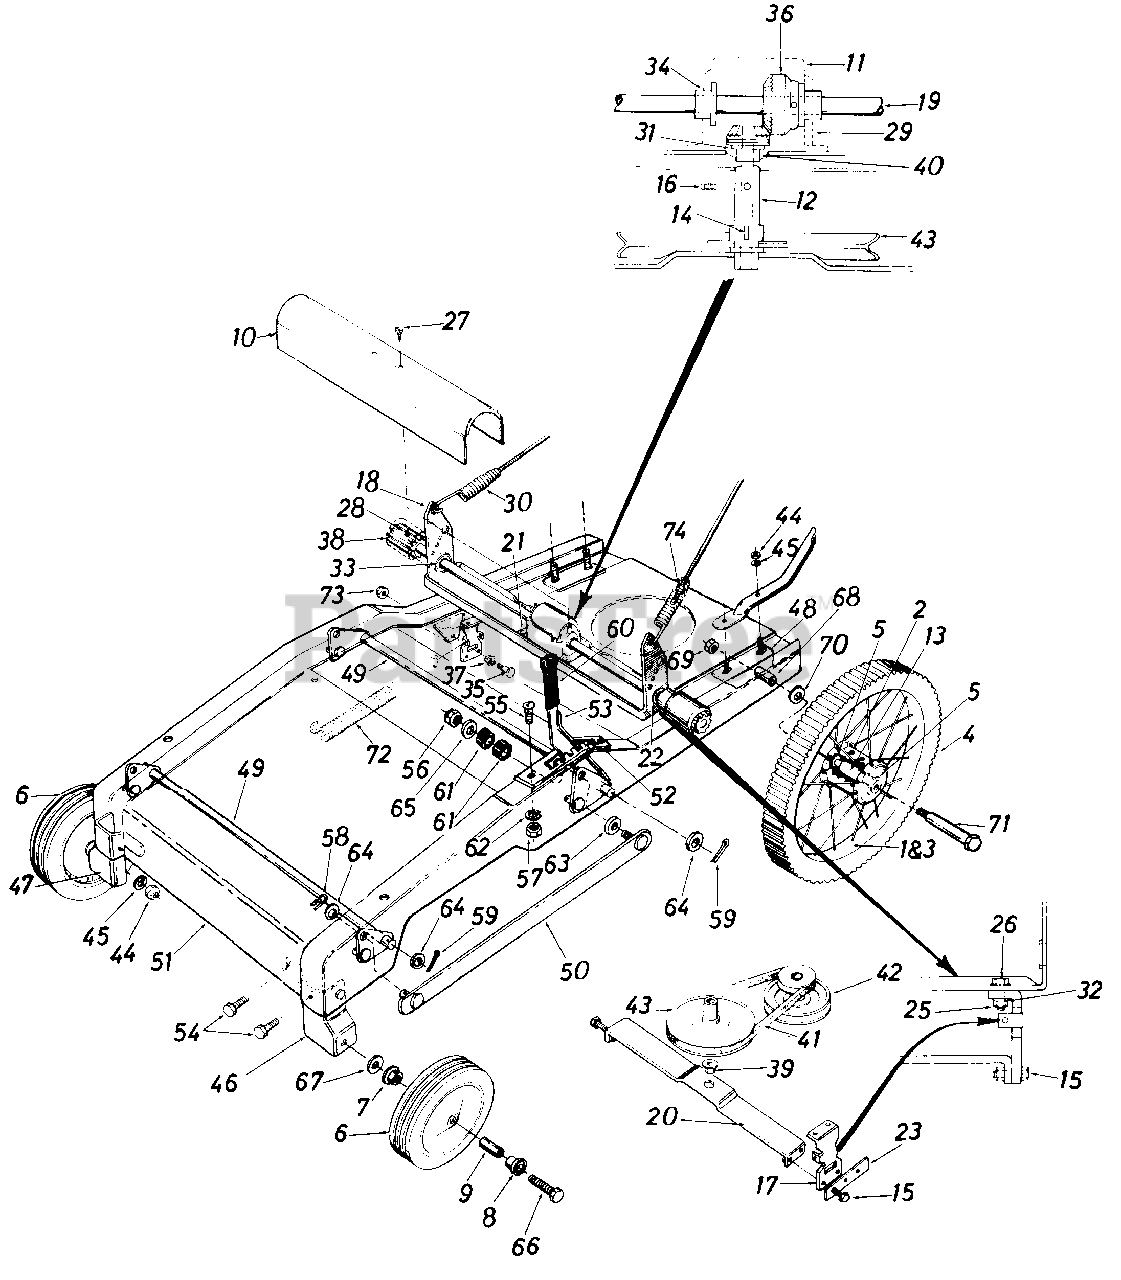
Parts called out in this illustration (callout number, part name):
1	16" Wheel Ass'y. Comp. Rear
2	Oil Cap
3	Rear Wheel Rim Only
4	Rear Wheel Ti re Only 16 x 1 .75
5	Ball Brg..630" I.D.
6	Wheel Ass'y. Comp. Front 8 "
7	Flanged Ball Brg. 3/8 I.D.
8	Flanged Ball Brg. 1/2" I.D.
9	Spacer 3/8 I.D
10	Top Drive Frame Cover
11	Gear Box Cover
12	Pinion Ass'y.
13	Wheel Spacer
14	#2 Wood ru f f Key 3/32 x 1/2" Dia. Hdn.
15	Hex Sems Bolt 5/16-18 x 1.00" Lg.
16	Set Scr. 5/16-18 x .25" Cup
17	Bottom Drive Frame
18	Top Drive Frame Ass'y.
19	Drive Shaft
20	Bottom Drive Frame Ass'y.
21	Hex Self-Tap Scr. 1/4-20 x .62" Lg.
22	Collar 5/8" I.D.
23	Drive Frame Stop
25	Hex Nut 5/16-18 Thd.
26	Hex Sems Bolt 5/16-18 x .75" Lg.
27	Hex Wash. Hd. AB-Tap Scr. #8 x .50" Lg.
28	Spring Pin 3/16" Dia. x 1.12" Lg.
29	Gear Box
30	Extension Spring
31	"O"-Ring
32	L-Wash. 5/16" I.D.
33	Ball Brg. .630" I.D.
34	Flange Brg. .630" I.D.
35	Shld. Bolt .443" Dia. x .330
36	Bevel Gear.62" I.D. 28 Teeth
37	Pivot Slide
38	Drive Pinion
39	Hex Flange Brg. .503" I.D.
40	Flange Brg. .503" I.D. w/G roove
41	3V-Belt 28" Lg.
42	Double Pulley
43	3/8" V-Pulley .502" I.D. x 6.5" O.D.
44	Hex L-Nut 3/8-16 Thd.
45	L-Wash. 3/8 I.D.*
46	Wheel Brk't. Ass'y. L.H.
47	Wheel Brk't. Ass'y. R.H.
48	Rear Wheel Brk't. Ass'y.
49	Lift Bracket Shaft Ass'y.
50	Connecting Link Ass'y.
51	Frame
52	Lift Handle Support Brk't.
53	Lift Handle
54	Hex Sems Bolt 5/16-18 x .75" Lg.
55	Carriage Bolt 5/16-18 x .62" Lg.*
56	Hex Ins. L-Nut 3/8-24 Thd.
57	Hex Nut 5/16-18 Thd.
58	Intern. Cot. Pin 5/16" Dia.
59	Cot. Pin 118" Dia. x 1.00" Lg.
60	Grip Black
61	Rubber Wash. .33" I.D. x .87" O.D.
62	L-Wash. 5/16" I.D.
63	Fl-Wash. .406" I.D. x 1.25" O.D. x .164
64	Fl-Wash. .510" I.D. x 1.0" O.D. x .060
65	Fl-Wash. .385" I.D. x .87" O.D. x .06
66	Hex Bolt 3/8-16 x 2.00" Lg.
67	Bell-Wash. .400" I.D. x .88" O.D.
68	Spacer.523" I.D. x .640" O.D. x 1.955
69	Hex Top L-Nut 3/8-16 Thd.
70	Fl-Wash. .531" I.D. x .93" O.D.
71	Shld. Bolt .498" Dia. x 4.755
72	Extension Spring .56" O.D. x 8.25" Lg.
73	Hex Ins. L-Nut 5/16-18 Thd.
74	Hex Ins. L-Nut 1/4-20 Thd.
